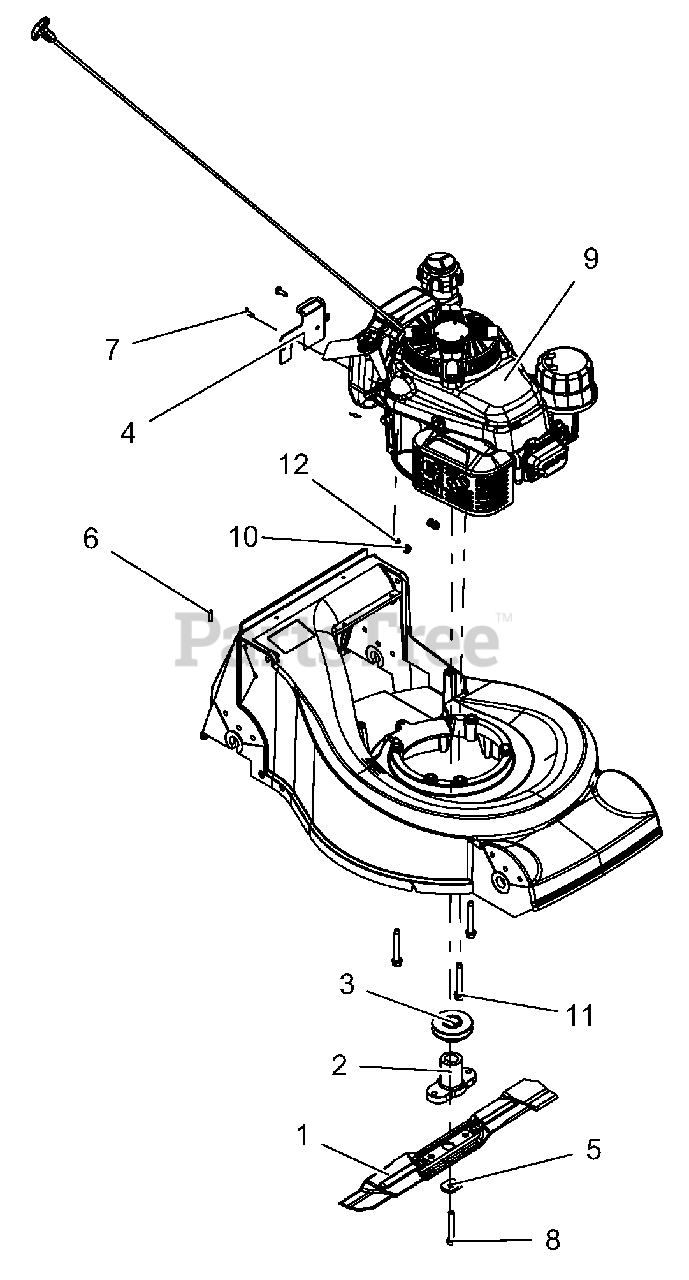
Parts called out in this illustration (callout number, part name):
1	BLADE, MOWER 21" HIGH-LIFT
2	ADAPTOR, BLADE
3	PULLEY, SP, KAWI, ZONE
4	BRKT, FUEL TANK
5	WSHR, SPRG
6	KEY-SQ .250X.250X.750
7	BLT-HEX .25-20X.75 GR5 YWZC
8	BLT-HEX .38-24X2.5 GR8 YWZC
9	ENGINE, KAWASAKI CARB
10	NUT, LK-TOP-FLG .25-20 YWZC
11	SCR-TAP.375-16X2.75 HWH TR YZ
12	WSHR-FL-STL.250X.562X.049YWZC
